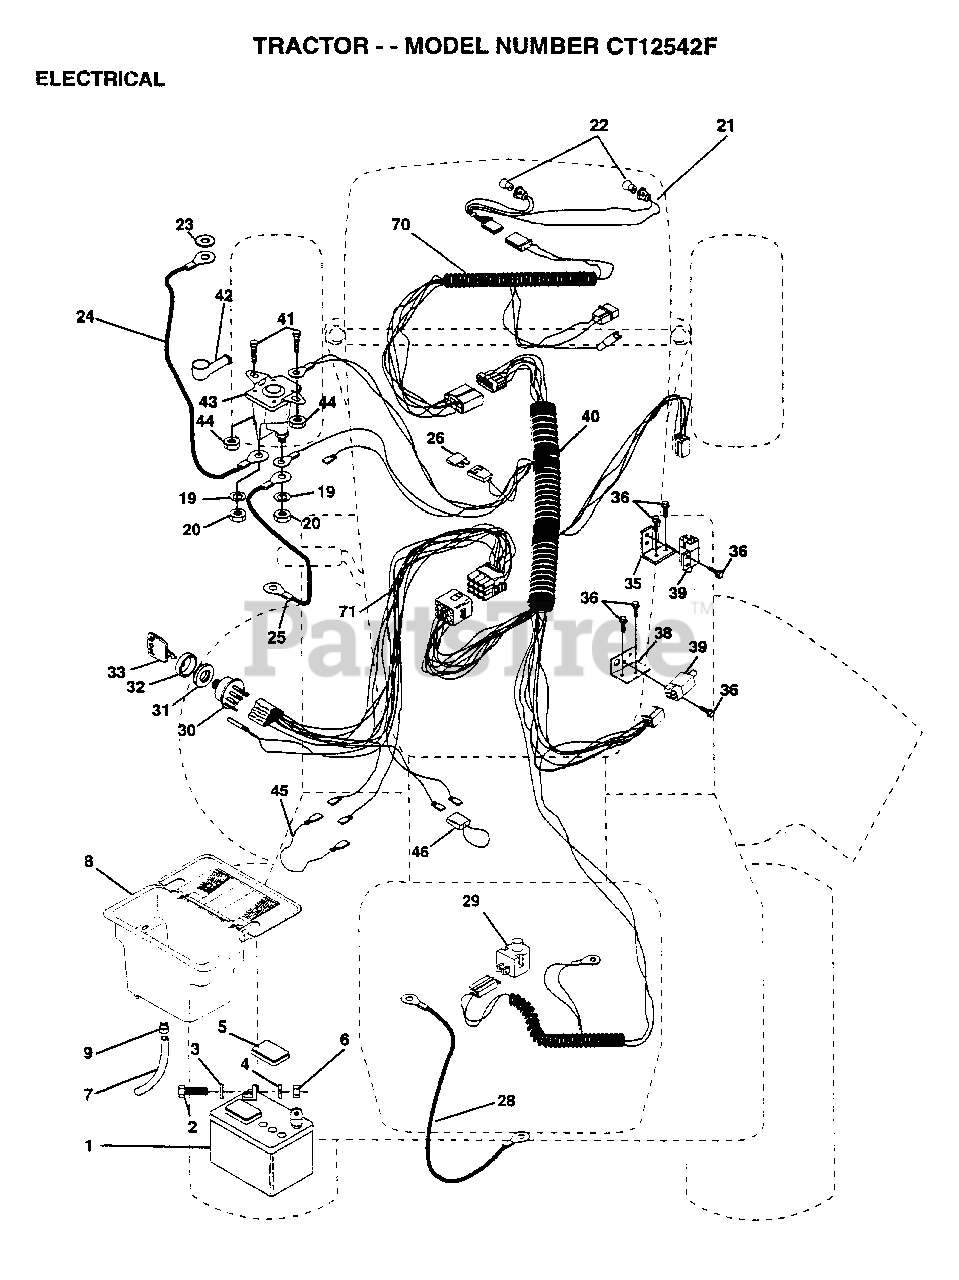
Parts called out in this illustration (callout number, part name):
2	BOLT LT
3	WASHER
4	LOCKWASHER
5	"CAP,BATTERY "
7	TUBE T
9	HOSE CLAMP T
20	NUT
21	"HARNESS,LIGHT SOC"
22	HEADLAMP BULB
23	LOCKWASHER
25	"CABLE T, BATTERY"
26	FUSE HYT
28	CABLE T
29	SWITCH SEAT
30	SWITCH IGN 4POS
31	NUT IGNITION
32	COVER KEY SWITCH
33	KEY
35	BRACKET LT
36	SCREW
38	BRACKET SWITCH IN
39	SWITCH INTERLOCKT
40	HARNESS IGN B&S
41	BOLT HXHD FIN
44	NUT HXKEP 1/4X20
45	ADAPTER AMMETER
46	PROTECTION LOOP
70	HARNESS.ENGINE
71	HARNESS DASH LT
